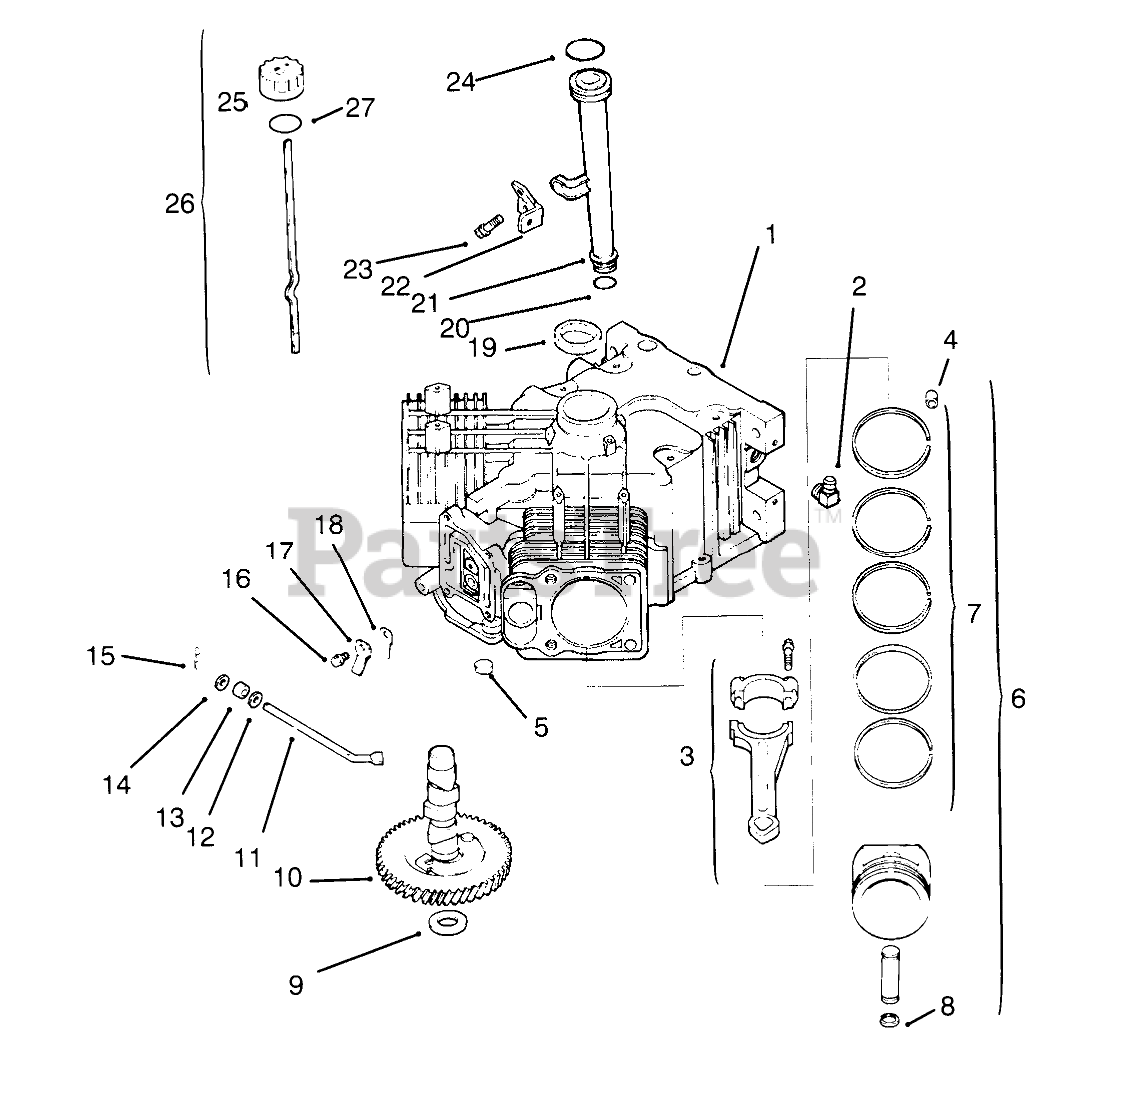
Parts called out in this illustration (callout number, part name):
1	Short Block (Only On: 72103)
2	Connector-90 DEG (Only On: 72103)
3	Connecting Rod STD (Only On: 72103)
3	Connecting Rod .25 (Only On: 72103)
4	Dowel-Locating (Only On: 72103)
5	Plug-Cup (Only On: 72103)
6	Piston ASM STD INCL 4/7/8 (Only On: 72103)
6	Piston ASM .25 INCL 4/7/8 (Only On: 72103)
6	Piston ASM .50 INCL 4/7/8 (Only On: 72103)
7	Ring Set STD INCL 4/8 (Only On: 72103)
7	Ring Set .25 INCL 4/8 (Only On: 72103)
7	Ring Set .50 INCL 4/8 (Only On: 72103)
8	Retainer-Piston Pin (Only On: 72103)
9	Shim-Camshaft A/R (Only On: 72103)
10	Camshaft (Only On: 72103)
11	Shaft-Governor Cross (Only On: 72103)
12	Washer-Flat (Only On: 72103)
13	Seal-Governor Shaft (Only On: 72103)
14	Washer-Flat (Only On: 72103)
15	Pin-Governor Hitch (Only On: 72103)
16	Screw M5x0.8x10 (Only On: 72103)
17	Retainer-Reed (Only On: 72103)
18	Beed-Breather (Only On: 72103)
19	Seal-Oil (Only On: 72103)
20	O Ring-Lower Fill Tube (Only On: 72103)
21	Tube-Oil Fill (Only On: 72103)
22	Bracket-Oil Fill Tube (Only On: 72103)
23	Screw M5X0.8X16 (Only On: 72103)
24	O Ring-Upper Fill Tube (Only On: 72103)
25	Dipstick INCL 26-27 (Only On: 72103)
26	Kit-Oil Cap INCL 3 (Only On: 72103)
27	O Ring-Fill Cap (Only On: 72103)
